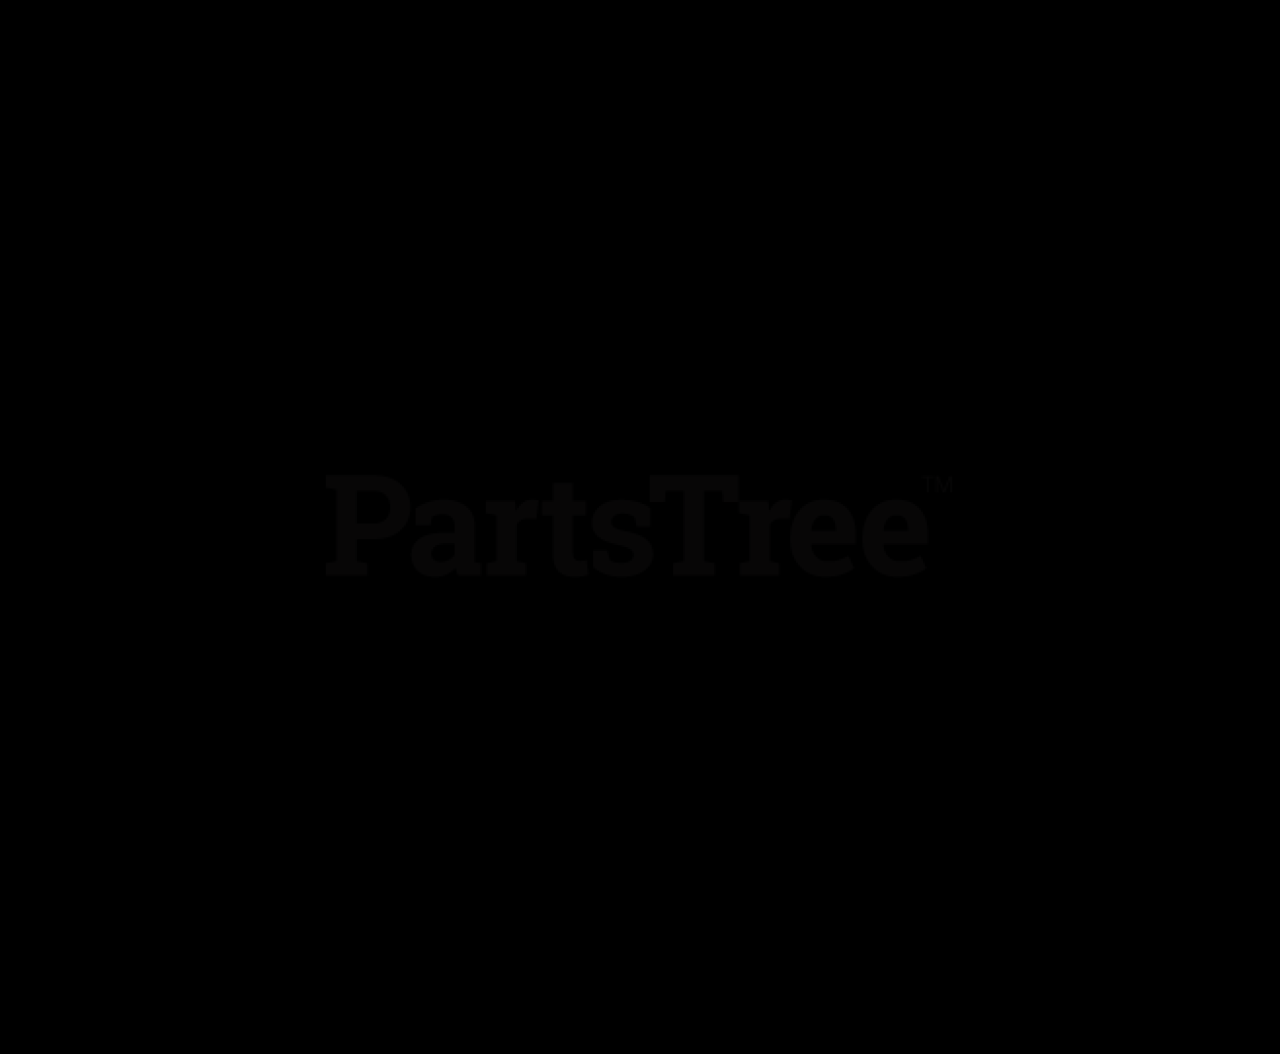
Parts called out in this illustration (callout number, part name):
1	Valve, Hydraulic
2	Nut, Locking-Center .31-18
3	Bolt, Hex .31-18 x 2.00 Grade 5
4	Bracket, Valve Mounting
5	Screw, Tapping .38-16 x .50 Hex Washer Head
6	Washer, Flat-Steel .515 x 1.625 x .25
7	Cylinder, Lift
8	Strap, Height of Cut Indicator
9	Bushing .516 x 1.00 x 1.05
10	Bolt, Hex .62-11 x 2.25 Grade 8
11	Washer, Lock .62 x .156
12	Rod End, Right Hand Female .625
13	Nut, Locking Center .62-11
14	Nut, Jam .625-18
15	Bolt, Hex .50-13 x 3.75 Grade 5
16	Nut, Locking Top Flange .50-13
17	Stop, Cylinder .34 Thick
18	Stop, Cylinder .68 Thick
19	Nut, Jam .75-16
20	Washer, Wave .076 x 1.12 x .08
21	Latch, Floor Board
22	Bushing, Flange .515 x .75 x .275 x 1.12
24	Washer, Locking .31X.078 Regular
